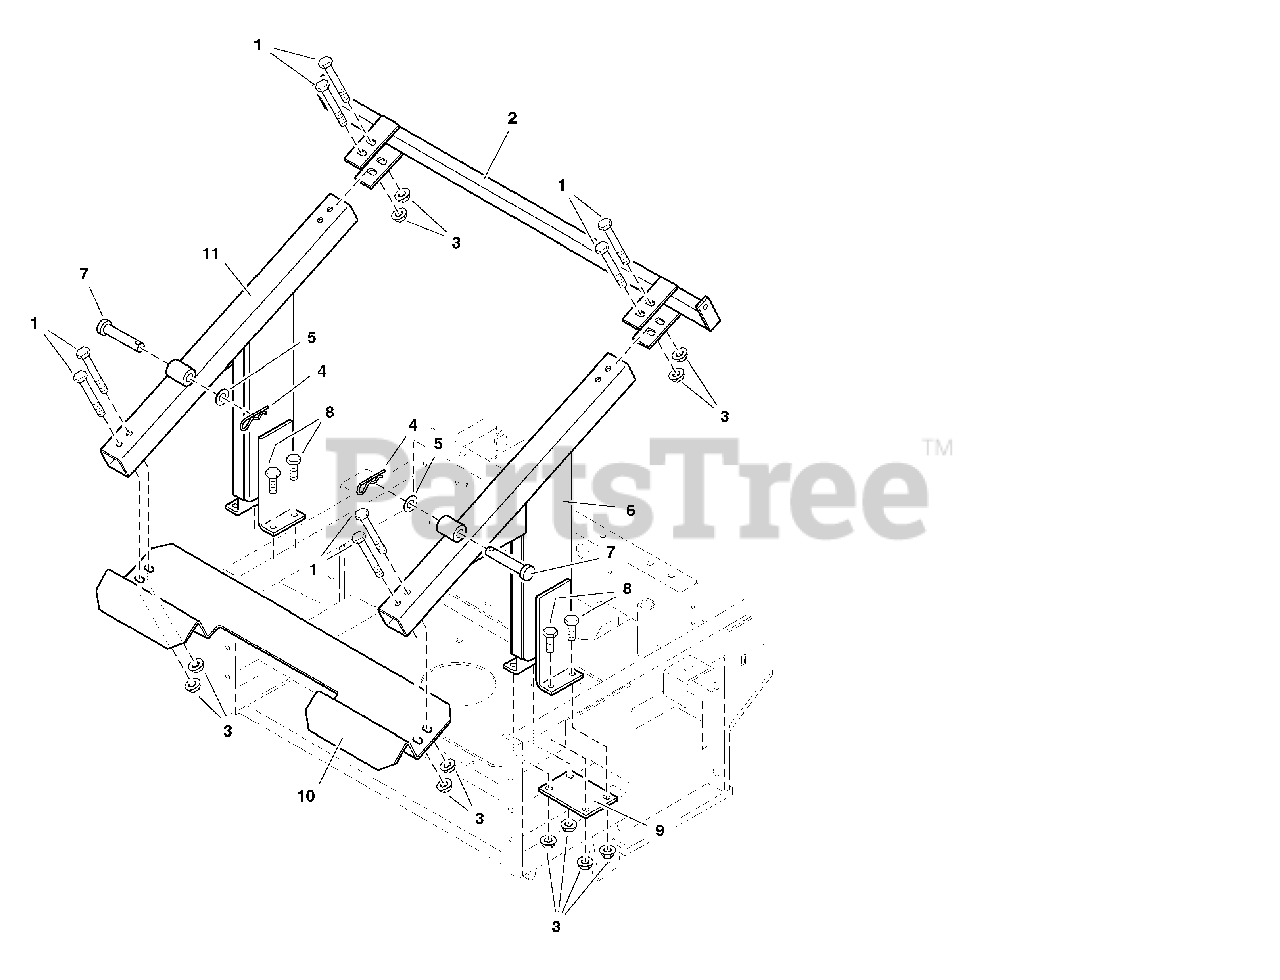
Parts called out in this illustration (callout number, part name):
1	BOLT, 3/8-16 x 3
2	FRONT CROSS MEMBER
3	NUT, 3/8-16 Hex Serrated Flange
4	HAIRPIN CLIP
5	WASHER, 5/8" SAE
6	FRAME UPRIGHT - RH
7	PIN, Clevis, 5/8 x 3
8	BOLT, 3/8-16 x 1-1/4
9	BOTTOM BRACE
10	REAR CROSS SUPPORT
11	FRAME UPRIGHT - LH
